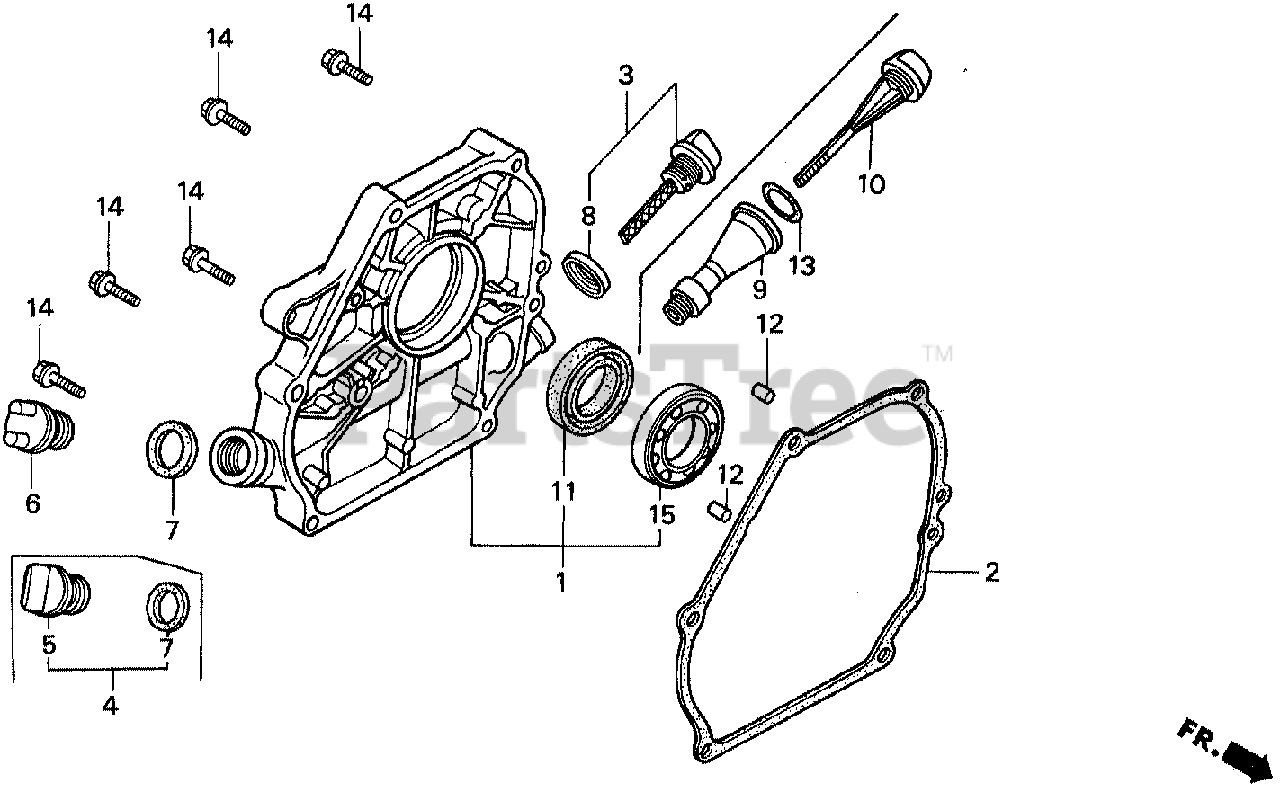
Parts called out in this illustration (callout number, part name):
1	COVER ASSY., CRANKCASE (W-TYPE)
2	GASKET, CASE COVER (NON-ASBESTOS)
3	CAP ASSY., OIL FILLER
4	CAP ASSY., OIL FILLER
5	CAP, OIL FILLER
6	CAP, OIL FILLER
7	GASKET, OIL FILLER CAP
8	GASKET, OIL FILLER CAP
11	OIL SEAL (25X41X6)
12	PIN A, DOWEL (8X14)
14	BOLT, FLANGE (8X32)
15	BEARING, RADIAL BALL (6205)
